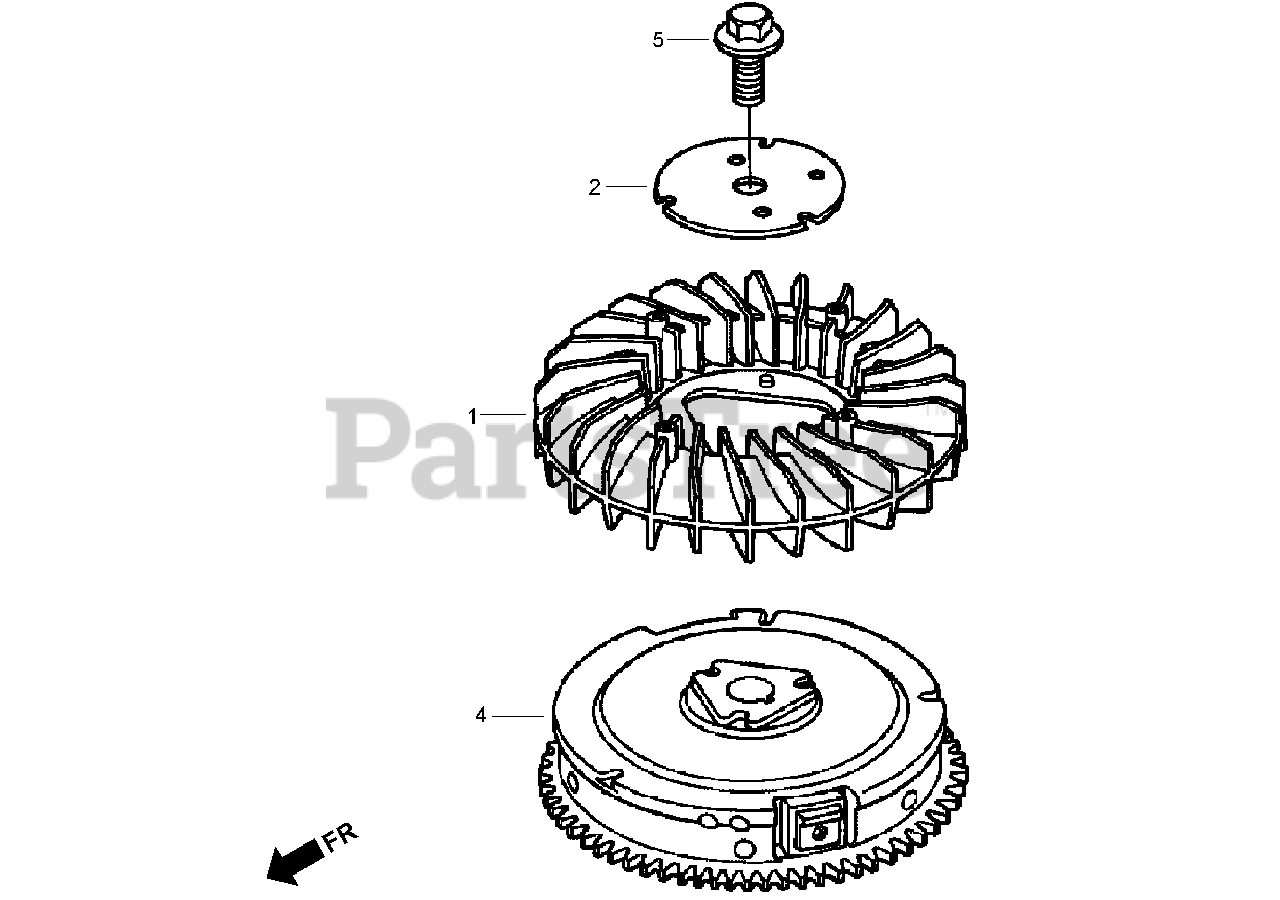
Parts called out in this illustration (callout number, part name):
1	FAN-COOLING
2	PLATE-SETTING, COOLING FAN
4	FLYWHEEL (6P)
5	BOLT-FLANGE (16X35)
